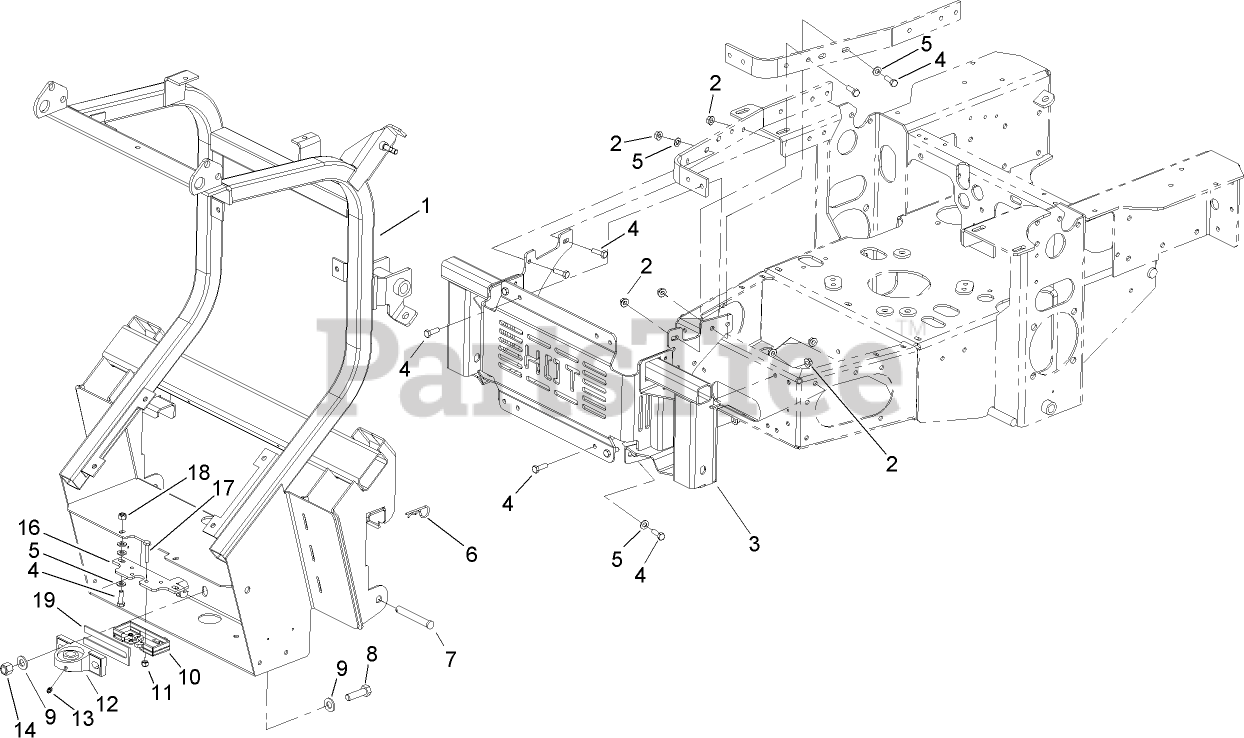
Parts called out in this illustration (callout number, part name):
1	Frame ASM
2	NUT-HF
3	Bagger Mount ASM
4	SCREW-HH
5	WASHER-PLAIN
6	PIN-COTTER
7	PIN-CLEVIS
8	SCREW-HH
9	WASHER-FLAT
10	LATCH-ROTOR
11	NUT-LOCK, NI
12	BEARING
13	FITTING-GREASE
14	NUT-LOCK, NI
16	BRACKET-LATCH
17	SCREW-HH
18	NUT-HF
19	SPACER-BEARING
